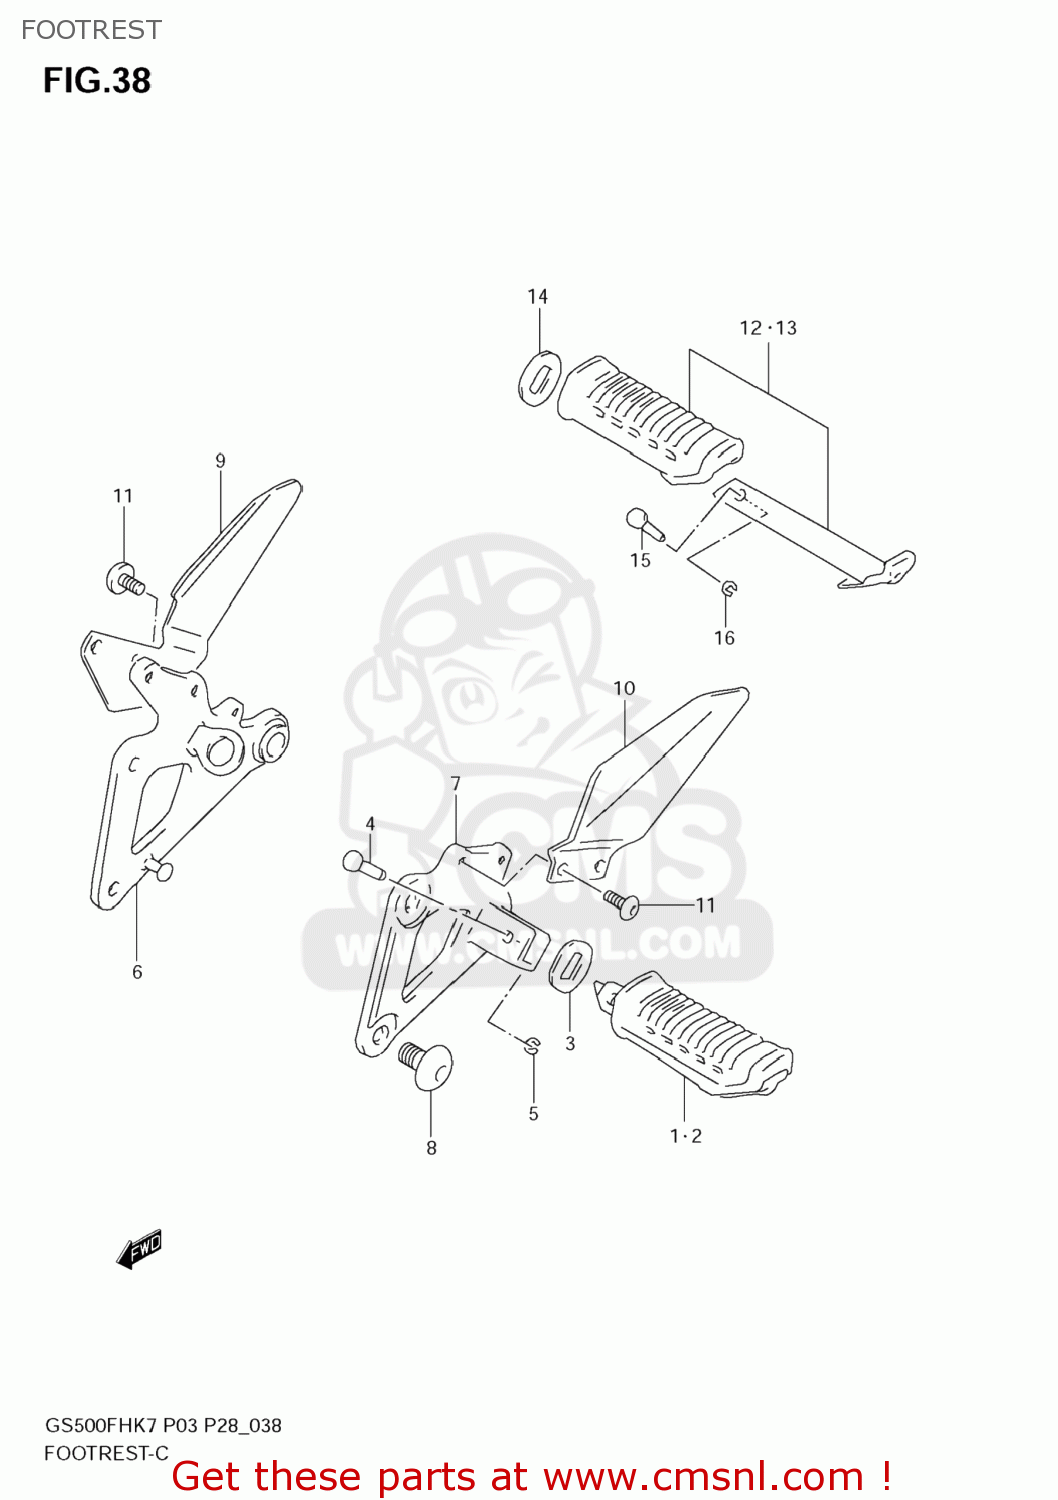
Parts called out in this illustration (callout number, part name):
1	RUBBER ASSY, FRONT RH
2	RUBBER ASSY, FRONT LH
3	WASHER,FOOTREST RUBBER
4	PIN(6X29.5)
5	E RING
6	BRACKET, FRONT RH (BLACK)
7	BRACKET, FRONT LH (BLACK)
8	BOLT(8X20)
9	GUARD,FR FOOTREST,R
10	GUARD,FR FOOTREST,L
11	SCREW(6X12)
12	FOOTREST ASSY,PILLION,R
13	FOOTREST ASSY,PILLION,L
14	WASHER,FOOTREST RUBBER
15	PIN(6X29.5)
16	E RING
